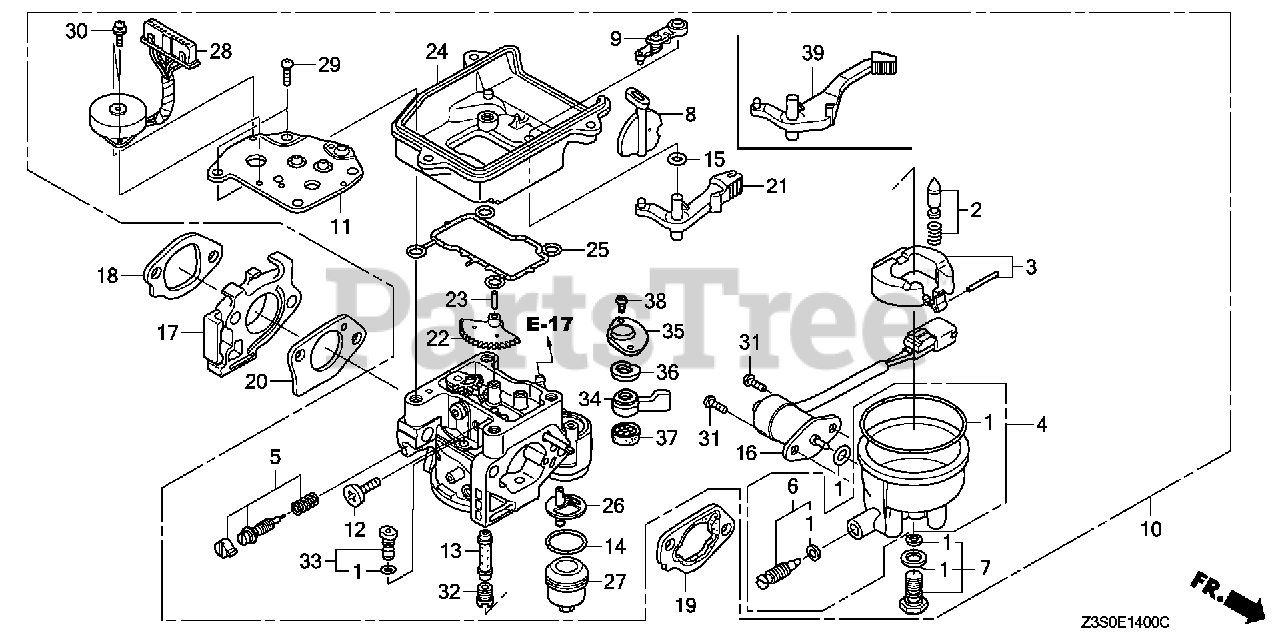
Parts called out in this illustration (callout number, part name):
1	GASKET SET
2	VALVE SET, FLOAT
4	CHAMBER SET, FLOAT
6	SCREW SET, DRAIN
7	SCREW SET
8	CHOKE SET (CARBURETOR NO.)
9	ARM, CHOKE (CARBURETOR NO.)
10	CARBURETOR ASSY. (BE89M C)
11	PLATE, MOTOR (CARBURETOR NO.)
12	SCREW, THROTTLE STOP
13	NOZZLE, MAIN
14	GASKET, FUEL STRAINER CUP
16	VALVE ASSY., SOLENOID
17	INSULATOR, CARBURETOR
18	GASKET, INSULATOR
19	SPACER, CARBURETOR
20	GASKET, CARBURETOR
22	GEAR, MIDDLE
23	SHAFT, GEAR CENTER
24	CASE, MOTOR
25	GASKET, MOTOR CASE
26	FILTER, CUP
27	CUP, FUEL STRAINER
28	MOTOR, THROTTLE CONTROL
29	SCREW, PAN (5X20)
30	SCREW-WASHER (3X6)
31	SCREW-WASHER (5X12)
32	JET, MAIN (#98)
32	JET, MAIN (#100)
32	JET, MAIN (#102)
33	JET SET, PILOT (#45)
39	LEVER, CHOKE
